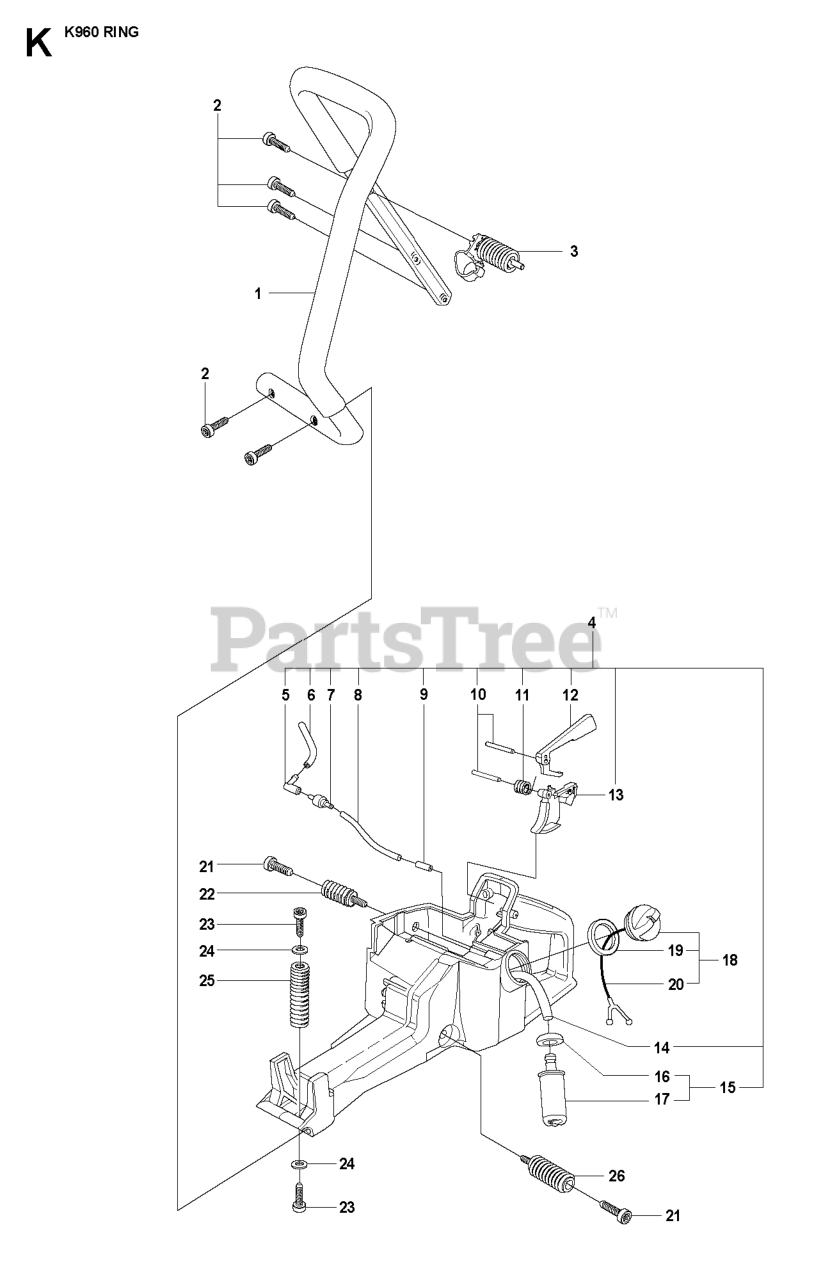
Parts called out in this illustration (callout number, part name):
3	%VIBRATION ABSORBER
4	FUEL TANK
6	HOSE
8	FUEL HOSE
10	PIN 3X25
12	THROTTLE LOCKOUT
13	THROTTLE TRIGGER
14	FUEL HOSE
15	FILTER
18	TANK CAP ASSY
22	AV ELEMENT
24	WASHER 5.3X12
25	SPRING FRONT
